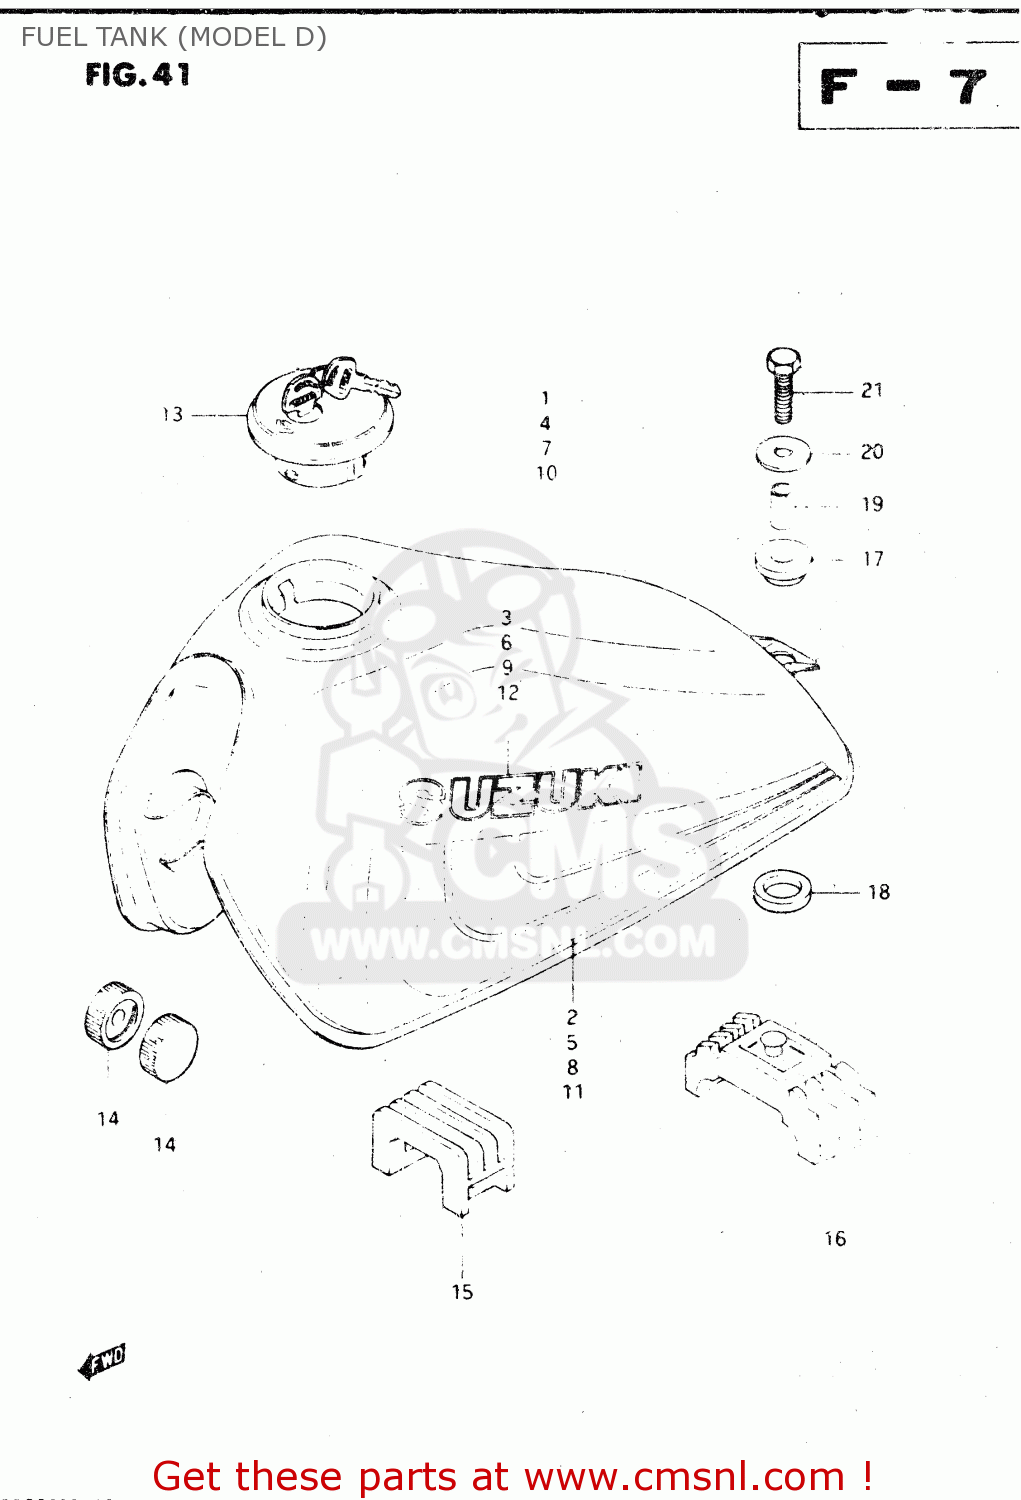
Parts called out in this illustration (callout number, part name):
1	TANK ASSY, FUEL (BLACK)
2	TAPE SET, FUEL TANK
3	EMBLEM,FUEL TANK(WHITE)
4	TANK ASSY, FUEL (BLUE)
5	TAPE SET, FUEL TANK
6	EMBLEM,FUEL TANK(WHITE)
7	TANK ASSY, FUEL (RED)
8	TAPE SET, FUEL TANK
9	EMBLEM,FUEL TANK(WHITE)
10	TANK ASSY, FUEL (WHITE)
11	TAPE SET,FUEL TANK
12	EMBLEM
13	CAP SET,FUEL TANK
14	CUSHION
15	CUSHION,TANK UPR FR
16	CUSHION,FUEL TANK,REAR
17	CUSHION
18	CUSHION
19	SPACER(8.5X12X19)
20	WASHER (8.5X29X1.6)
21	BOLT (8X30)
